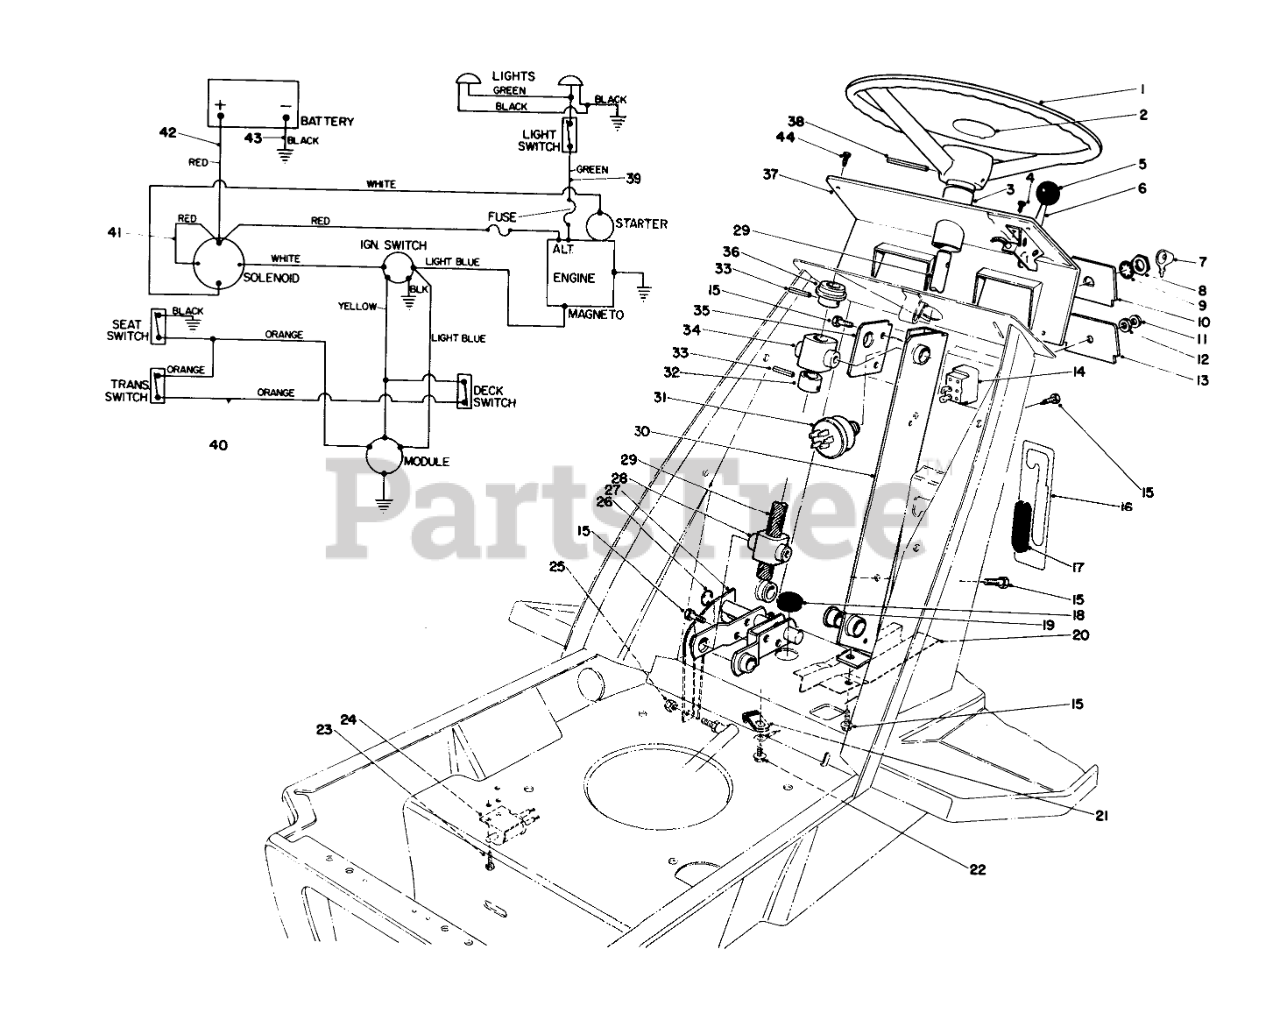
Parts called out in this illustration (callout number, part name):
1	Steering Wheel
2	Cap Steering Wheel (Model #57351)
3	Tube Steering
5	KNOB-CONTROL
6	Throttle Control (Incl. Ref. #5)
7	Key
8	NUT-HH
9	WASHER-TOOTH, INTERNAL
10	DASH PANEL INSERT
11	NUT-BULB
12	NUT-LOCK
13	DASH PANEL INSERT
14	Light Switch (Incl. Ref. #11 & 12) (Model #57351)
15	SCREW-HWHTF
16	Decal-Deck Engagement
17	EDGE MOULDING
18	GROMMET
19	BEARING-FLANGE
20	Shield Wire Harness
21	CLIP-FUEL LINE
22	SCREW-HWH
23	SCREW-TAPTITE
24	DECK INTERLOCK SWITCH
25	Nut
26	E-RING
27	Steering Link
28	Follower Steering Shaft
29	Steering Shaft
30	Bracket-Steering
31	Ignition Switch (Incl. Ref. #8 & 9)
32	STRG SHAFT COLLAR
33	PIN-SPRING
34	Bearing-Steering Shaft
35	STRG BRG SUPPORT
36	Collar Steering Shaft
37	DASH PANEL
38	PIN-ROLL
39	Wire Harness Light
40	Wire Harness
41	SOLENOID WIRE
42	WIRE ASM
43	WIRE ASM
44	SCREW-HWHTF
